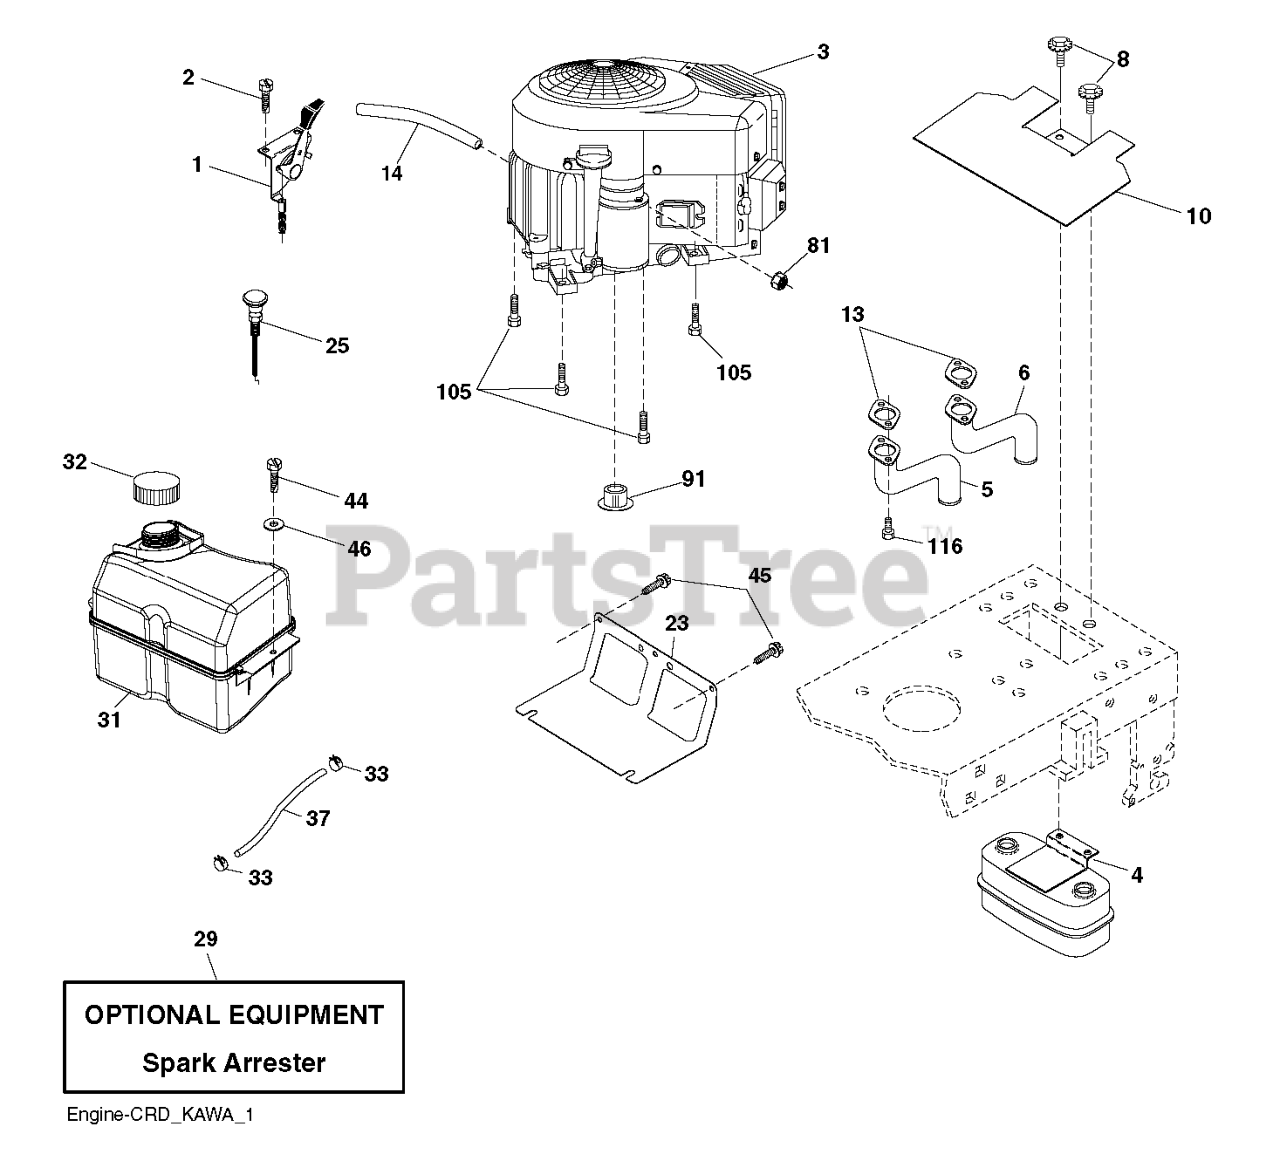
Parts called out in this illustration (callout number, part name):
1	THROTTLE CABLE
2	SCREW.#10 X 0.750.BOS
4	MUFFLER.TWIN.CYL.LOW.TONE
5	EXHAUST TUBE LH KAWI
6	EXHAUST TUBE RH KAWI
8	BOLT.5/16-18UNCX3/4 W/SEMS.BLK
10	RP SHIELD HEAT MUFFLER
13	GASKET.EXHAUST.KAWASAKI.15-1
14	TUBE, DRAIN OIL ASM.
23	SHIELD.BROWNING.DBR.GUARD
25	CONTROL, CHOKE
29	KIT.SPARK ARRESTOR 794945 B&S
31	TANK.ASM.FUEL.FR.2.5GA.
32	CAP.FUEL.2.25"VENTED"
33	HOSE CLAMP
37	LINE.FUEL.20
44	SCREW HEXWSHR 1/4-20X3/4
45	SCREW, 3/8-16X3/4
81	NUT
91	BUSHING.1.375OD
105	SCREW 3/8-16X1
116	NUT.HEX.FLANGE.TOPLOCK
